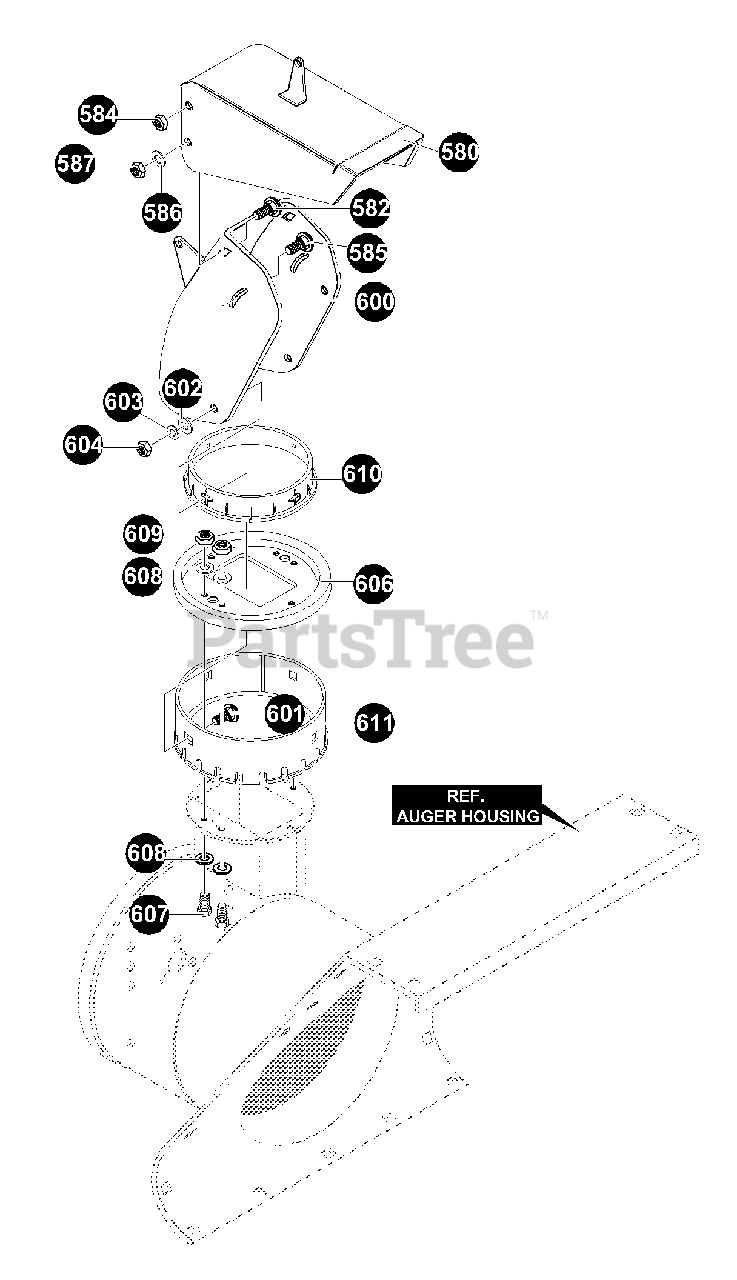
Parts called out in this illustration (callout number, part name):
580	CHUTE, UPPER
582	SCREW, 5/16-18X.75 SLTRMA
584	NUT, 5/16-18 HEXNYL
585	SCREW, 5/16-18X.75
586	WASHER, PLASTIC .315X.75X.064
587	NUT, 5/16-18 HEXNYL
600	CHUTE, LOWER
601	BOLT 5/16-18X1.00 CARR.
602	FLATWASHER .344X.69X.065
603	NUT 5/16-18 HEXNYL
606	COLLAR, CHUTE RECT.
607	SCREW 1/4-20X.75
608	FLATWASHER, .281X.63X.065
609	NUT, 1/4-20 REGHEXCTRLK
610	RETAINER, RING INNER
611	RETAINER, RING OUTER
